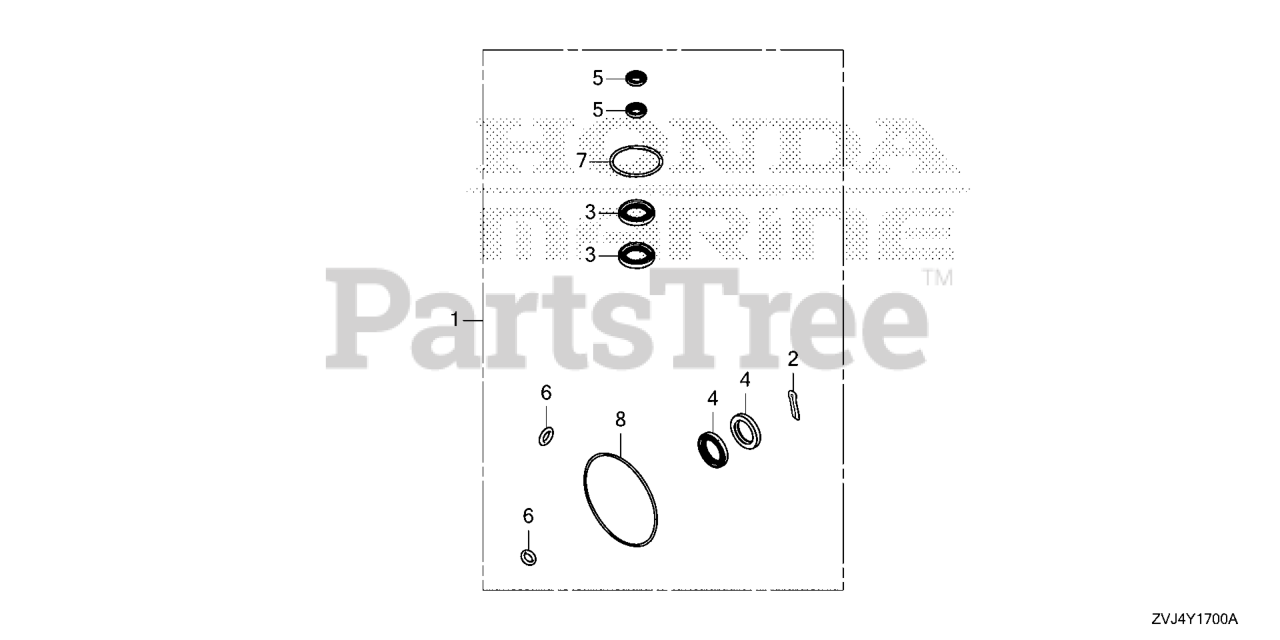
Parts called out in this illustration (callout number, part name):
1	CASE KIT, GEAR
2	PIN, SPLIT (4.0)
3	SEAL, WATER (26X42X7)
4	SEAL, WATER (30X45X7)
5	SEAL, WATER (12X21X6)
6	O-RING (6.9X1.45)
7	O-RING (49.4X3.1)
8	O-RING (121X3.1)
